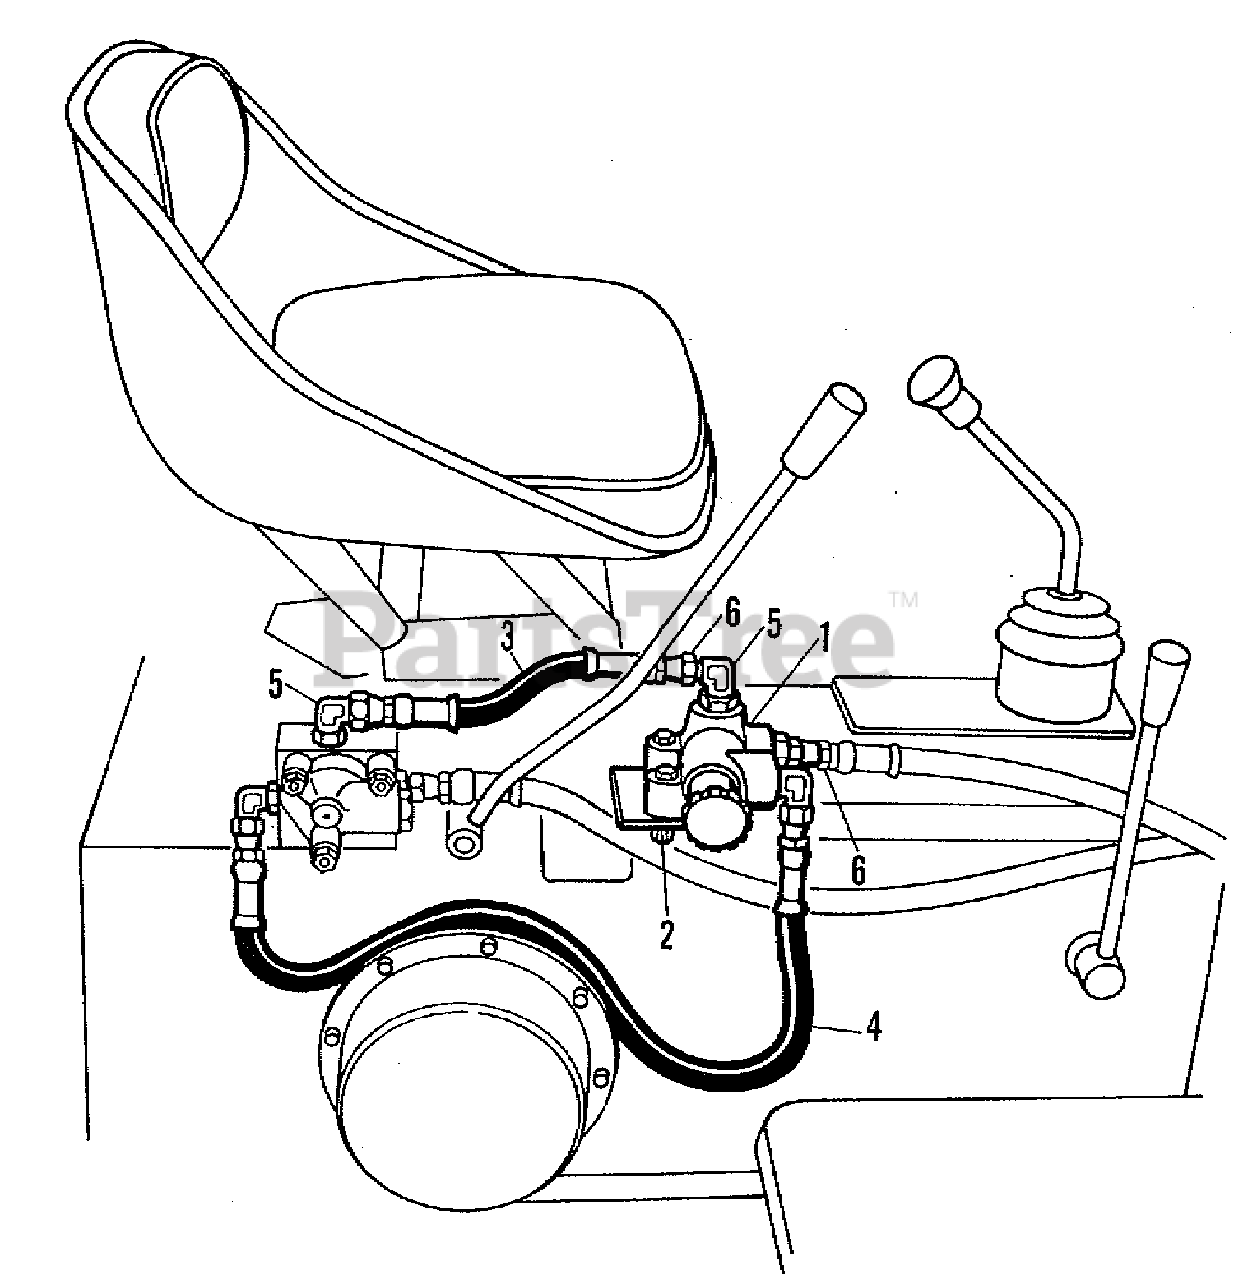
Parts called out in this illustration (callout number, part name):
1	VALVE ASSEMBLY, Selector
1	CAPSCREW, 5/16NC x 2
1	WASHER, Plain, 3/8 x 7/8 x No. 16
1	LOCKWASHER, 5/16
1	NUT, 5/16NC
2	MOUNTING, Valve
3	HOSE ASSEMBLY, 9" Long
4	HOSE ASSEMBLY, 28" Long
5	ADAPTER, Elbow
6	CONNECTOR, Straight
